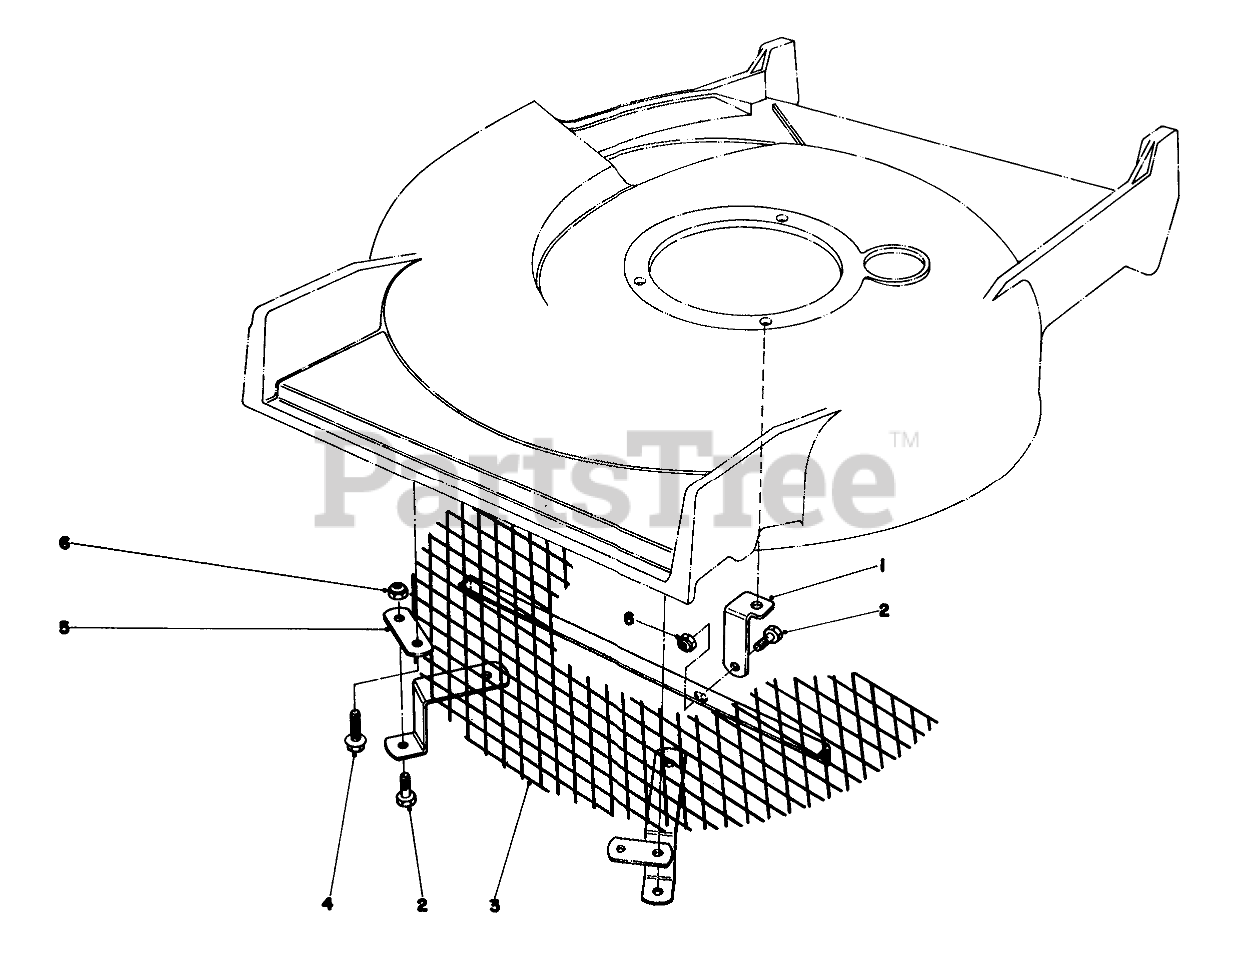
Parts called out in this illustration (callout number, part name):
1	Support Bracket
2	SCREW-HH
3	Screen
4	SCREW-HWHTF
5	ANCHOR
6	NUT-LOCK, NI
